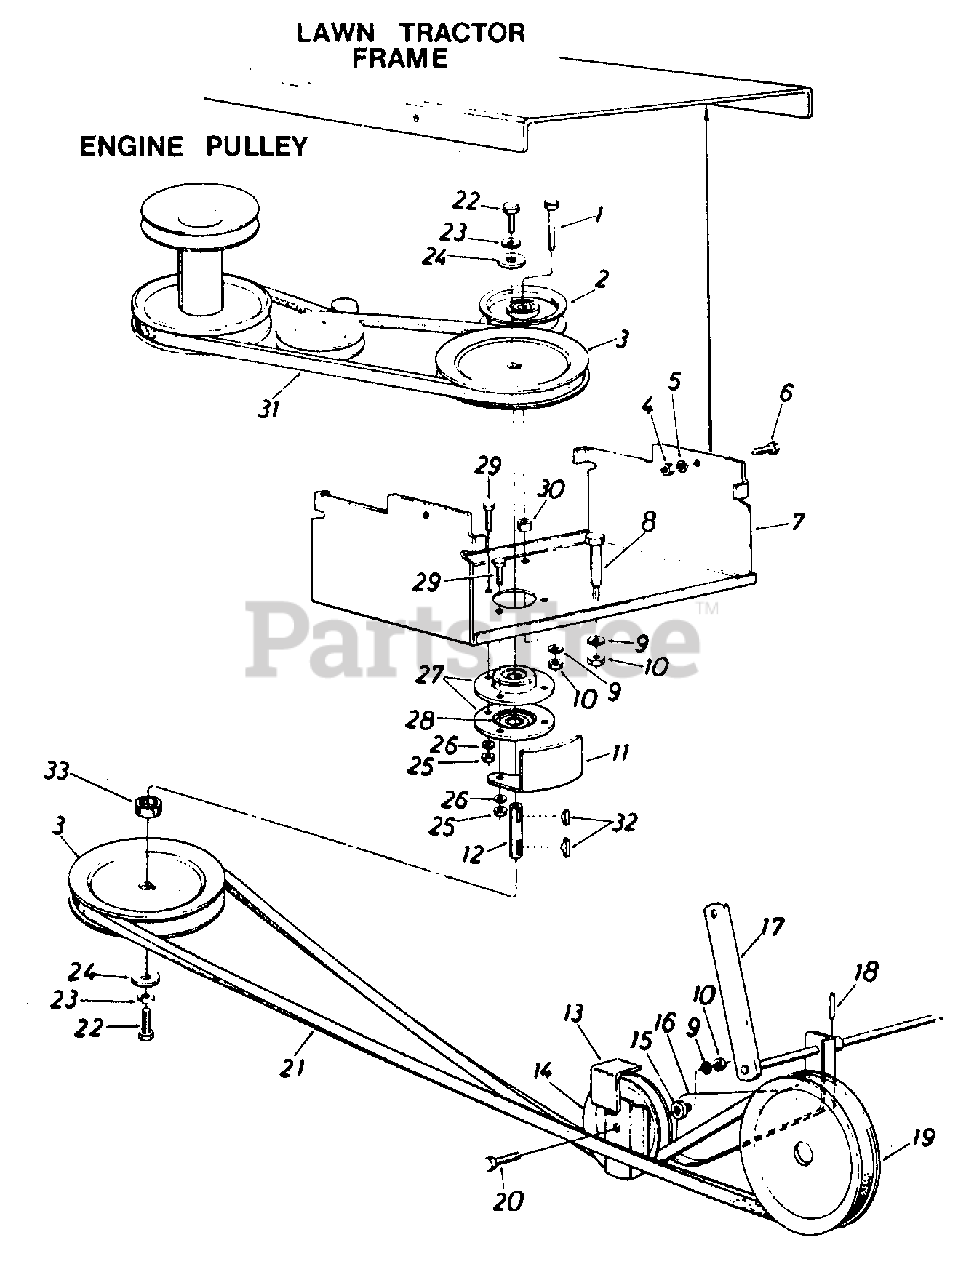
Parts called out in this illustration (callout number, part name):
1	Hex Bolt 3/8-16 x 2.00" Lg.*
2	Fl.-ldler w/ Flanges 3-3/4" O.D.
3	5/8" "V"-Pulley .790" I.D. x .650" O.D.
4	Hex N ut 3/8-24 Thd.*
5	L.-Wash. 3/8" I.D. Heavy Duty
6	Hex Bolt 3/8-24 x .88" Lg.*
7	Carriage Bracket
8	Shoulder Bolt .498" Dia. x 1.64
9	L.-Wash. 3/8" I.D.*
10	Hex Nut 3/8-16 Thd.*
13	Belt Separator Plate
14	Fl.-ldler w/ Flanges 3.25" O.D.
15	Fl.-Wash. .406" I.D. x 1.25" O.D. x .164
18	Spring Pin Roll 3/16" Dia. x 1.50" Lg.
19	5/8" V-Pulley 1.50" I.D. x 6.50" O.D.
20	Hex Bolt 3/8-16 x 1.75" Lg.*
21	"V"-Belt 1/2" x 95.0" Lg.
22	HexBolt5/16-18 x .88" Lg. Spec.
23	L.-Wash. 5/16" I.D.*
24	Fl.-Wash. .344" I.D. x 1.125" O.D. x .125
25	Hex Nut 5/16-18 Thd.*
26	L.-Wash. 5/16" I.D.*
27	Bearing Housing 1.85" I.D.
28	Ball Bearing .787" I.D. x 1.85" O.D.
29	Hex Sems Bolt 5/16-18 x .75"
31	Belt 1/2" Wide x 52" Long
32	Hi-Pro Key 3/16" x 5/8"
33	Spacer-.80" I.D. x 1.0" O.D.
